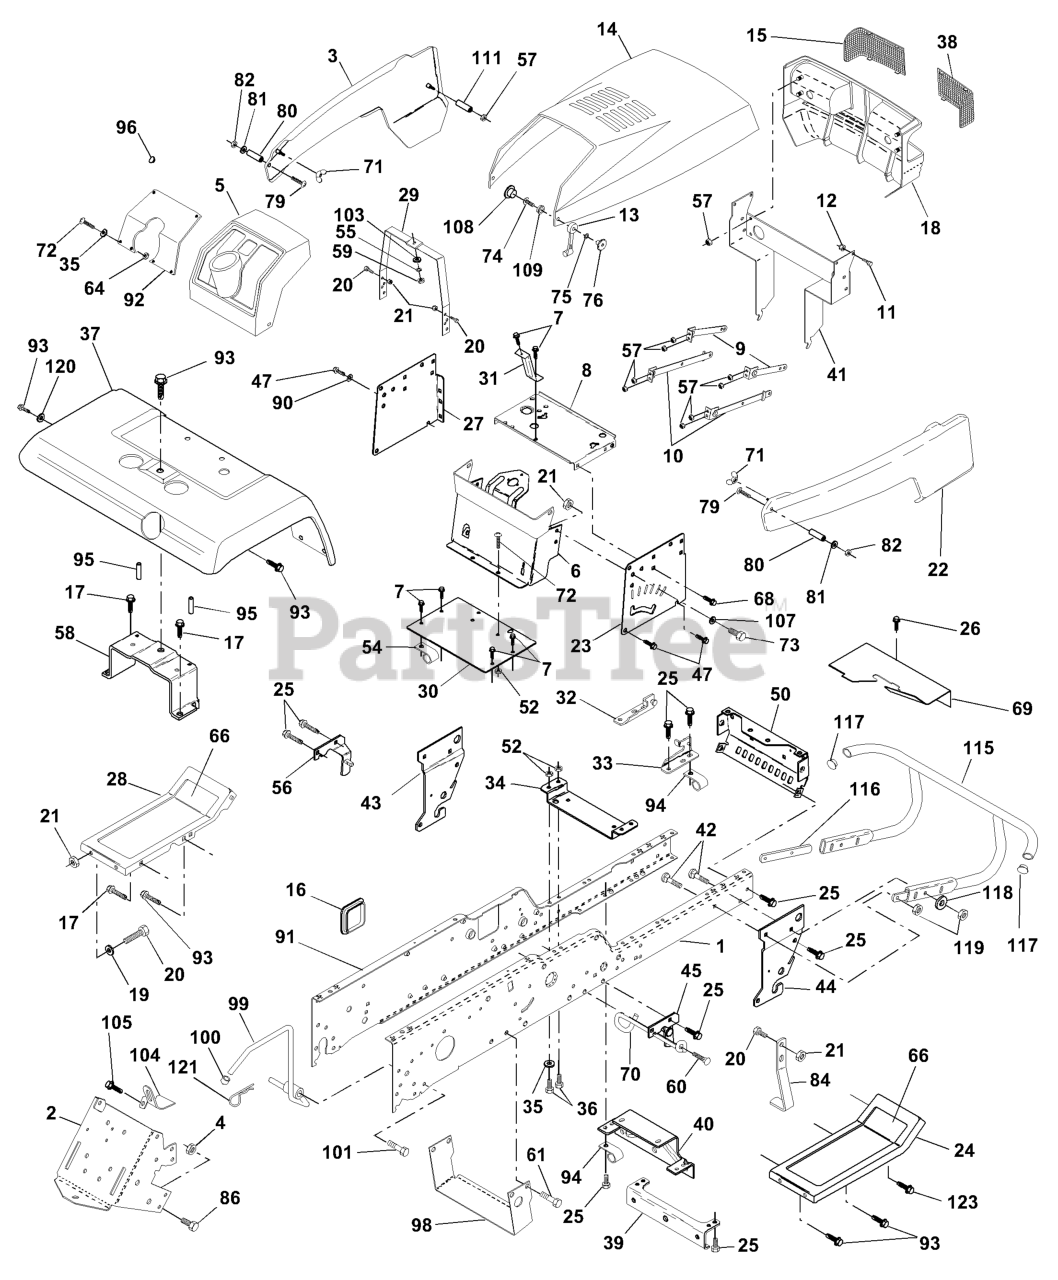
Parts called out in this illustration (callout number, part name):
1	FRAME RAIL RH
2	DRAWBAR-GT
3	SIDE PANEL ASSY LH
4	Nut, Lock Hex 7/16 Unc
6	LOWER DASH ASSY
7	SCREW
8	BATTERY SUPPORT
9	STRAP ASSY LT
10	STRAP ASSY LT
11	BOLT T
12	LOCKNUT.NYLOC.1/4-20
13	LATCH.HOOD.
14	HOOD.HUSQVARNA.ORANGE
15	LENS RH
16	COVER ACCESS
17	SCREW
18	GRILL COMPLETE
19	WASHER
20	BOLT
21	NUT
22	SIDE PANEL ASSY RH
23	PANEL, DASH RH
24	PAD,SPACER
25	SCREW
26	SCREW.THDROL.5/16-18X3/4.TTY
27	PANEL, DASH LH
28	ROLL PIN NLA
29	SUPPORT ASS'Y
31	STEERING SUPPORT BRACE
32	FRAME PIVOT BRKT ASSY LH
33	FRAME PIVOT BRKT ASSY RH
34	ENGINE SUPPORT BRKT
35	WASHER
36	BOLT.FIN.HEX.5/16-18X3/4
37	FENDER
38	LENS LH
39	FRONT AXLE BRACKET
40	AXLE SUPPORT BRKT
41	GRILL SUPPORT ASSY
42	BOLT.3/8-14X1.25
43	FRONT SUSPENSION BRKT LH
44	FRONT SUSPENSION BRKT RH
45	CHASSIS BRKT
47	SCREW LT
50	CHASSIS BRKT
52	NUT.71038.31-18.HEX.NYLOCK
54	CLIP,INSULATOR
55	WASHER PM
56	SUSPENSION BRKT LH
57	NUT
58	FENDER BRKT
59	NUT
60	SCREW
61	SCREW
62	RETAINER M
64	NUT
66	PAD FOOTREST T
68	Screw, Thdrol 5/16-18 x 1/2
69	HEAT SHIELD
70	BELT GUIDE
71	WING NUT
72	Screw, Mach Trhd 5/16-18 x 3/4
73	BOLT
74	SCREW
75	LOCKWASHER #10
76	WELDNUT
79	RP SCREW
82	NUT **
84	MOWER STOP
86	BOLT
90	LOCKWASHER
91	FRAME RAIL LH
92	DASH PLATE
93	SCREW LT
95	NUT-PUSH YT
96	PLUG-DASH T
98	BRACKET CHASSIS
99	ROD ASMBLY BYPASS
100	CAP
101	SCREW LT
103	LOCKWASHER
104	BRACKET LOCK BYPASS
105	Screw Thdrol. 5/16-18 x 1/2
106	SCREW
107	WASHER
108	SNAP CAP LT
115	BUMPER ASSY
116	BRACKET BUMPER
117	PLUG PLASTIC
118	WASHER
120	WASHER
